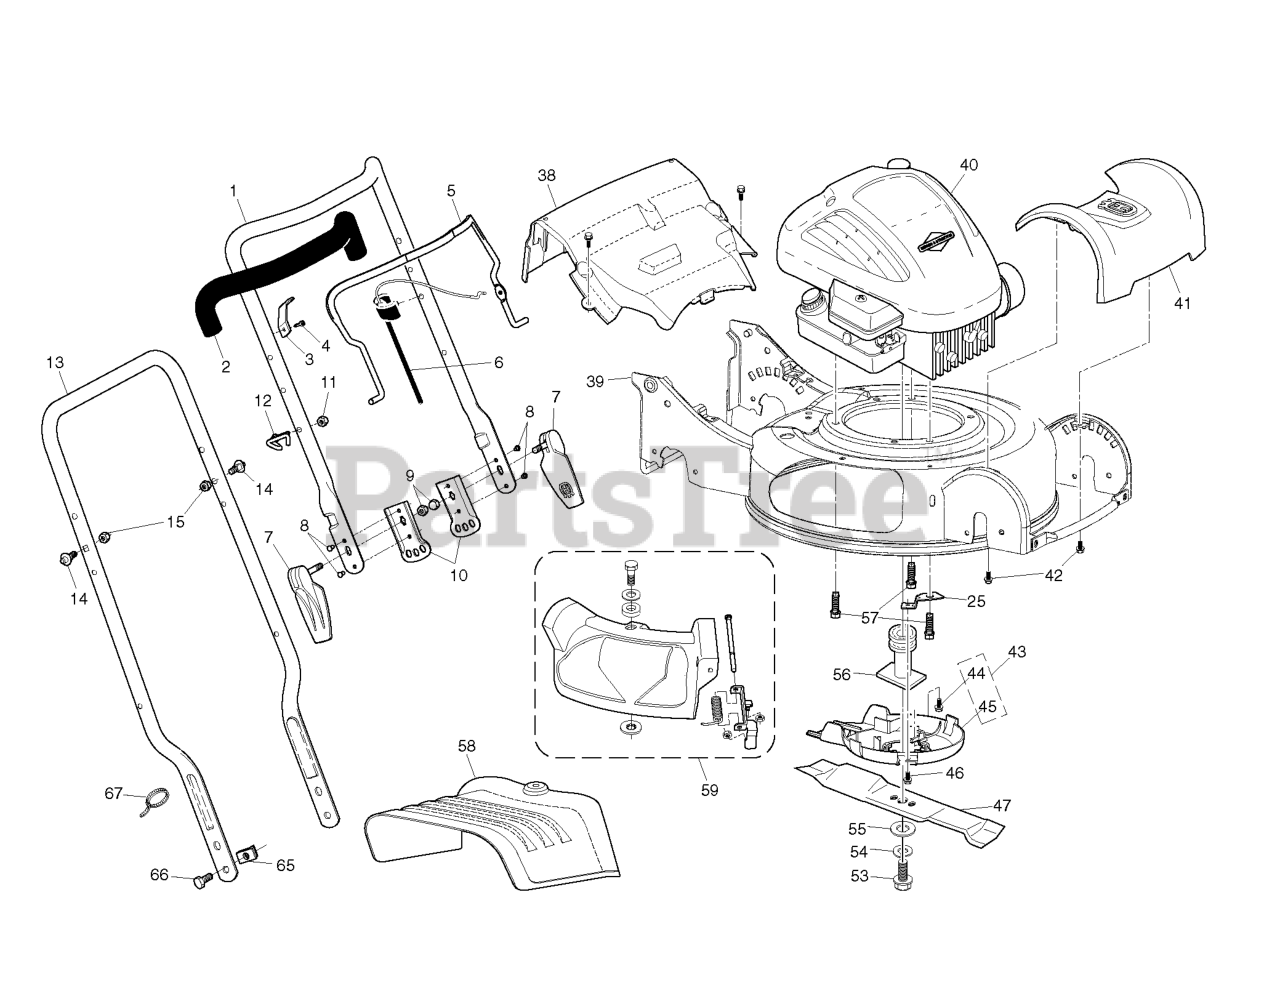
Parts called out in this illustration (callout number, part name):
1	HANDLE.ASM.UP.W/ADJ.BKT
2	GRIP.HANDLE.FOAM.WIDE.(1 SIDE)
3	BRACKET.UPSTOP.RT
5	BAIL.CONTROL.MZR.BS.ORANGE
6	CONTROL.ZONE.ASM
7	QUICK.ASM.RELEASE.BLACK
9	Locknut, Hex 1/4-20
10	BRACKET.ADJ.3POS.GREY
11	NUT
12	RB GUIDE.ROPE.STD.BLK.ZIN WSL
14	STUD.QUICK.ADJUST
15	NUT.LOCK.5/16-18
25	BRACKET
37	SCREW, HEX WASHER HEAD
42	SCREW.HWH.13-16-5.8.BZP
44	HINGE SCREW
46	SCREW.HEX.WSH
53	BOLT.HD.HEAD.3/8-24X2.50 (2 2)
54	LOCKWASHER
55	WASHER,HARDEN
57	BOLT 3/8-16X1-1/8
67	TIE GUIDE
